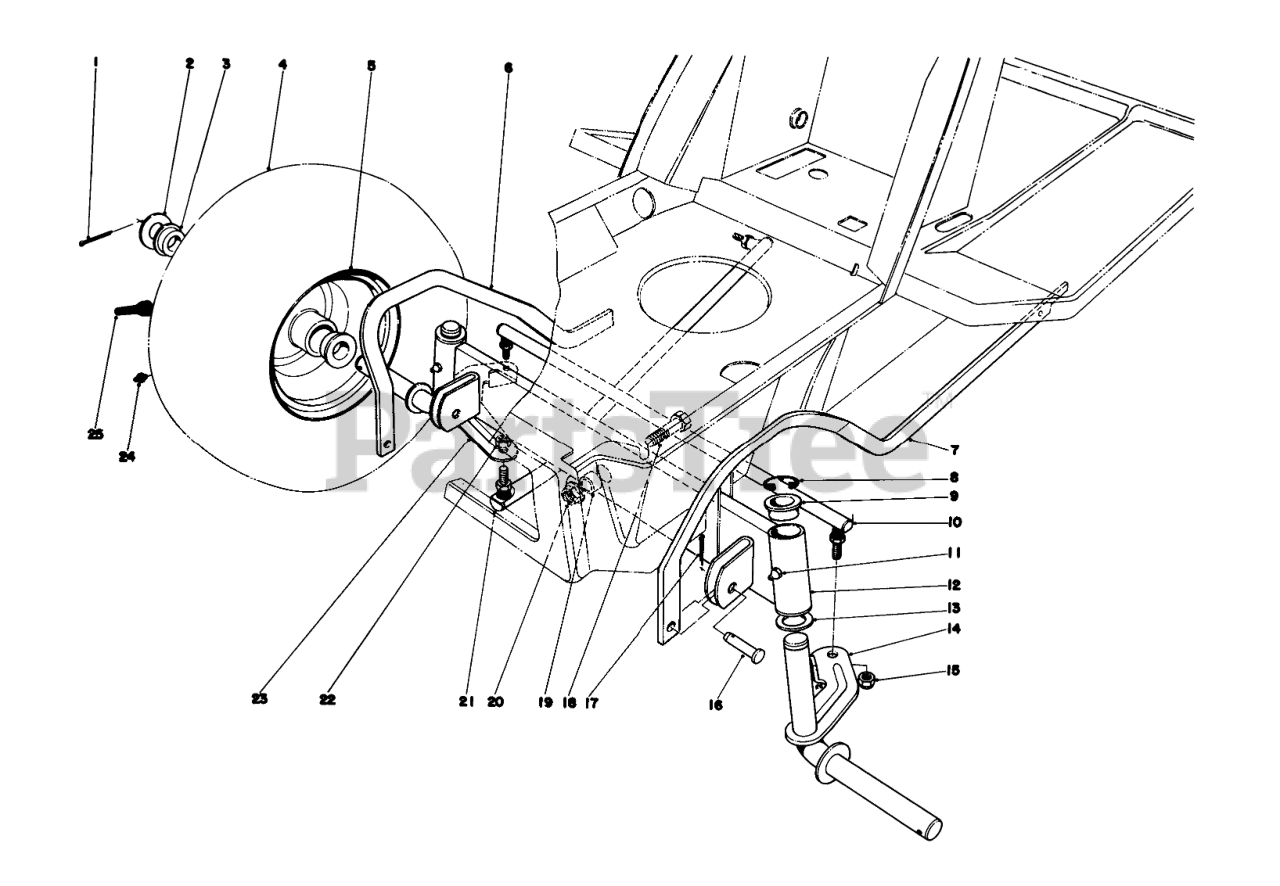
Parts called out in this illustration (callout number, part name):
1	PIN-COTTER
2	WASHER-PLAIN
3	WHEEL BSHG
4	Tire
6	RH DECK PARALLEL LINK R
7	LH DECK PARALEL LNKR
8	E-RING
9	BEARING-FLANGE
10	Tie Rod Steering
11	GREASE FITTING
12	FRONT AXLE WA
13	WASHER-THRUST
14	Spindle L.H.
15	NUT-LOCK NI
16	PIN-CLEVIS
17	PIN-COTTER
18	SCREW-HH
19	SPACER-AXLE, FRONT
20	NUT-HF
21	STEERING ARM B
22	Nut
23	SPINDLE WA RH B
24	FITTING-GREASE
25	STEM-VALVE
